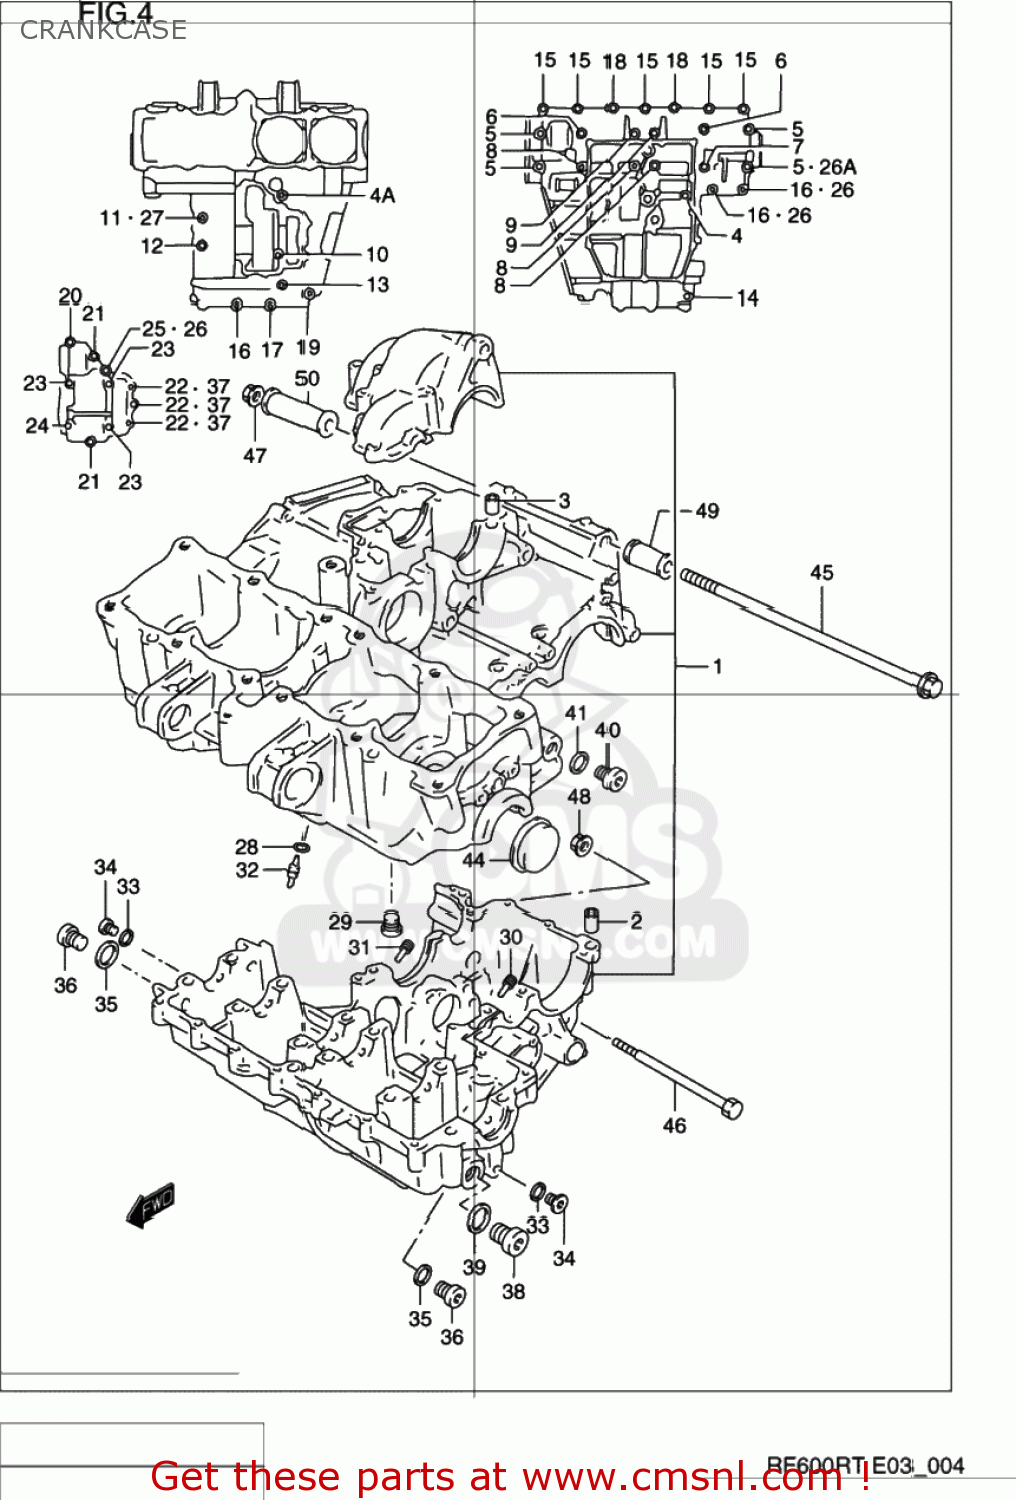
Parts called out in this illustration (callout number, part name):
1	CRANKCASE SET
2	PIN(10.4X13X22)
3	PIN
4	BOLT(6X105)
4A	BOLT(6X105)
5	BOLT 9X80
6	BOLT(9X95)
7	BOLT(9X105)
8	BOLT(9X115)
9	BOLT(9X60)
10	BOLT
11	BOLT
12	BOLT
13	BOLT
14	BOLT
15	BOLT
16	BOLT
17	BOLT
18	BOLT
19	BOLT
20	BOLT,CL.COVER
21	BOLT
22	BOLT
23	BOLT,CL.COVER
24	BOLT
25	BOLT(6X145)
26	GASKET(6.2X13X1.2) (NAS)
26A	GASKET(10.2X20X2).3 (NAS)
27	GASKET(8.2X14X1) (NAS)
28	O RING(D:1.2,ID:4)
29	PLUG,CRANKCASE,UPPER
30	JET
31	JET(140)
32	JET(13)
33	GASKET(10X14X3.6) (NAS)
34	PLUG(10X6.8)
35	GASKET(16X22X2) (NAS)
36	PLUG
37	GASKET(5.8X11X1.2) (NAS)
38	PLUG(22X11)
39	GASKET(22X27X2) (NAS)
40	PLUG
41	GASKET(13.8X18.8X4.8) (NAS)
42	BEARING,CRANK THRUST(GREEN)
43	BEARING,CRANK THRUST(RED)
44	PLUG
45	BOLT 10X280
46	BOLT(12X140)
47	NUT
48	NUT 12MM
49	SPACER,ENG MTG RR UPR,L(L45)
50	SPACER,ENGINE MOUNT
